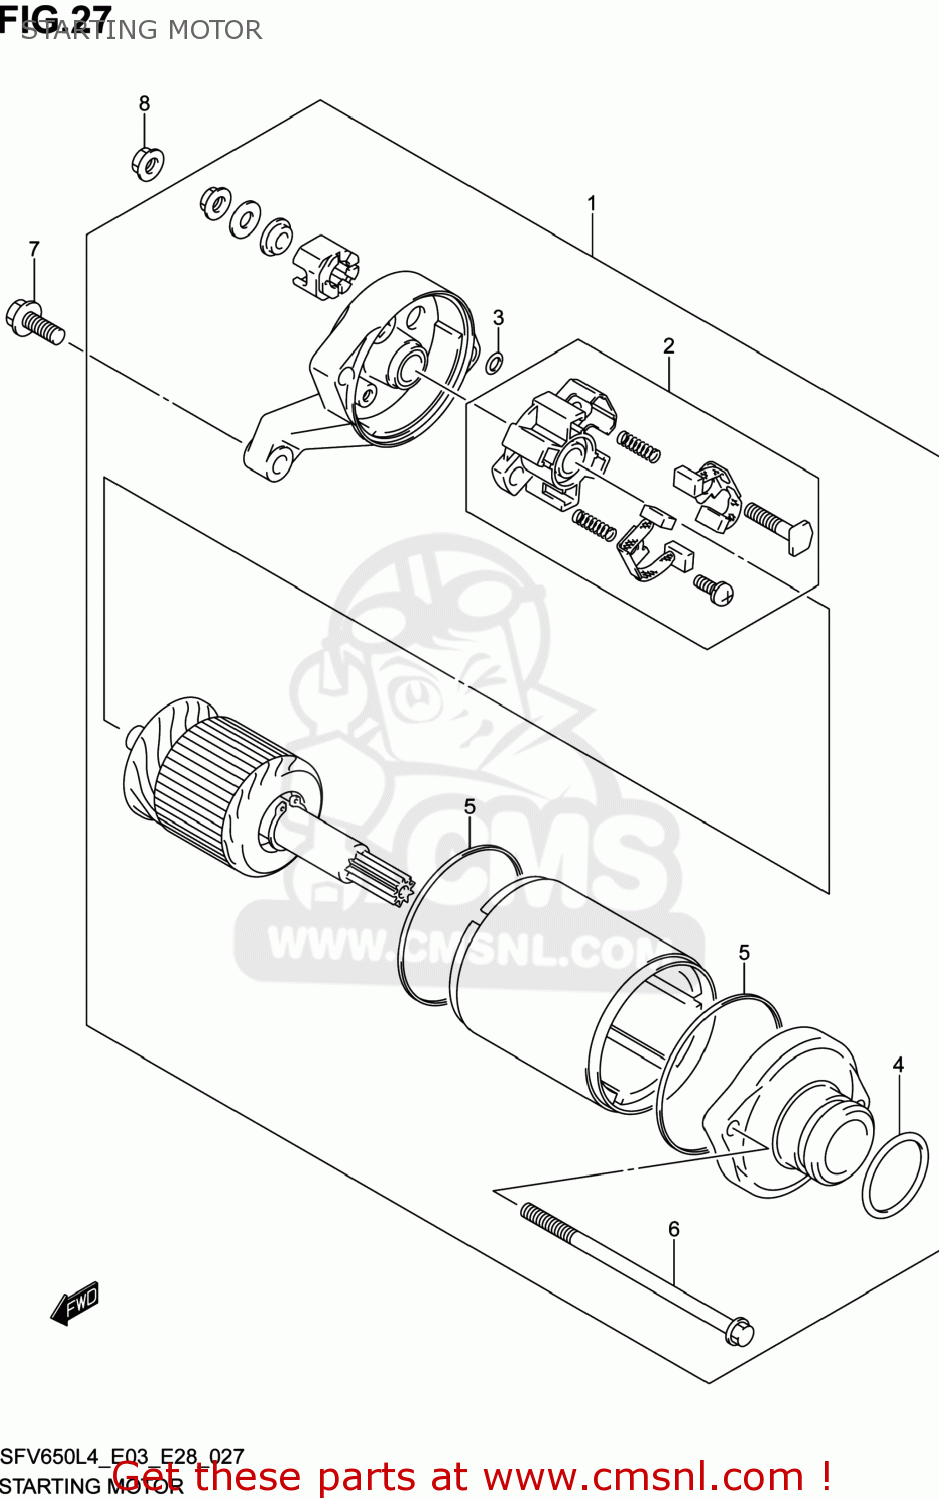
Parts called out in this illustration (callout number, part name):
1	MOTOR ASSY,STARTING
2	BRUSH HOLDER SET
3	O RING
4	O RING
5	SQUARE RING
6	SET,BOLT
7	BOLT(6X25)
8	NUT
